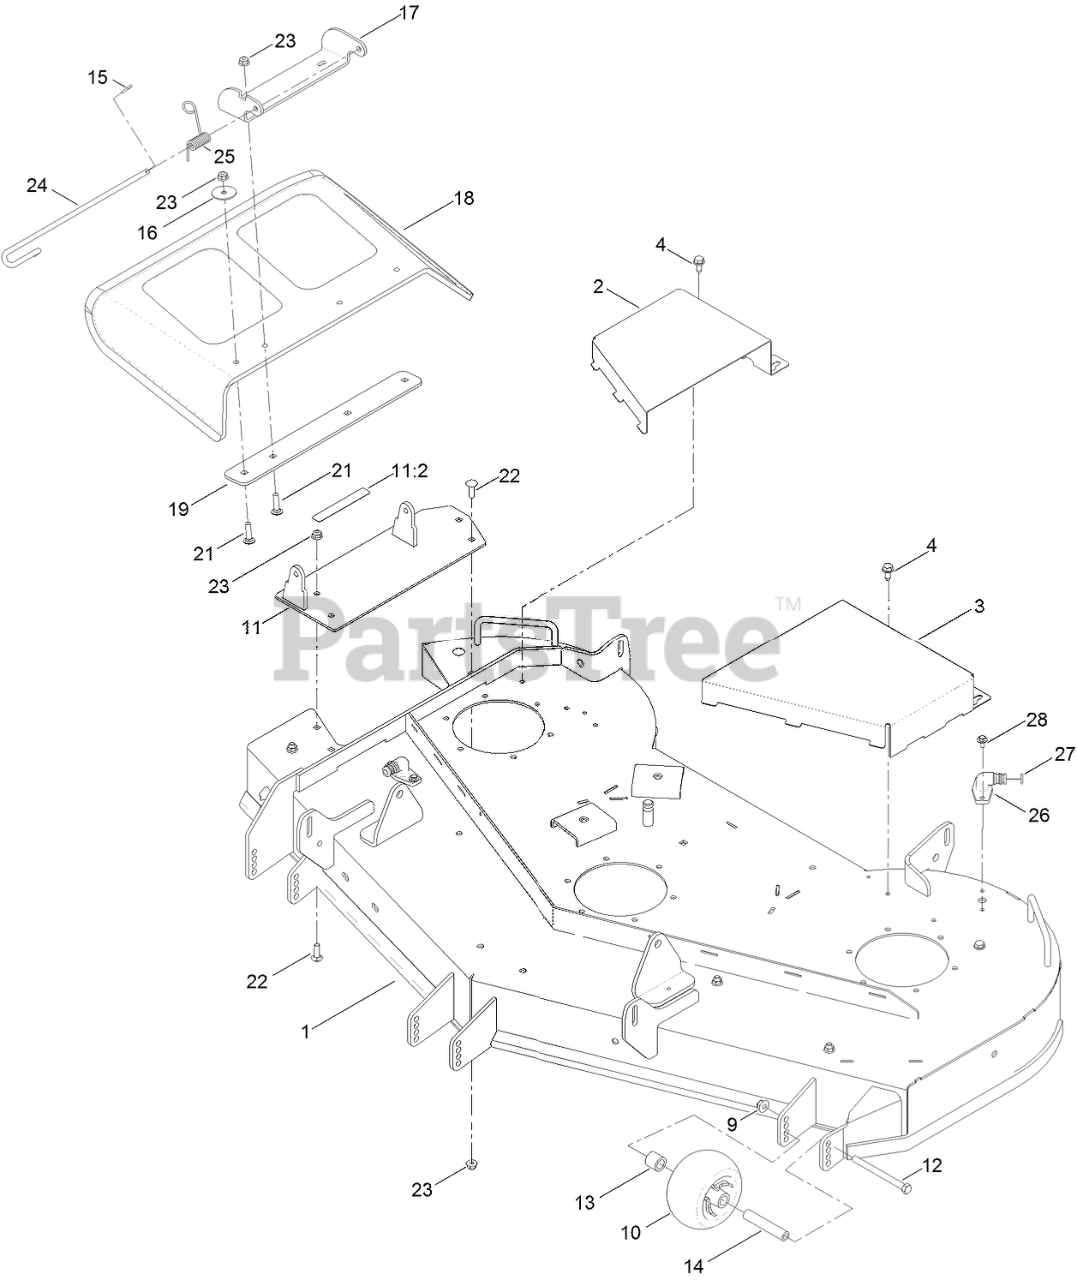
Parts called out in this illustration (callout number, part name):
1	54 INCH DECK ASM
2	COVER-BELT, RH
3	COVER-BELT, LH
4	SCREW-HWHTF
9	NUT-HF, NI
10	ROLLER-SCALP, ANTI
11	PIVOT-DEFLECTOR
11:2	DECAL-DANGER
12	SCREW-HH
13	SPACER-AXLE, REAR
14	TUBE-SPANNER
15	PIN-COTTER
16	WASHER-FLAT
17	BRACKET-DEFLECTOR, UPPER
18	DEFLECTOR
19	PLATE-DEFLECTOR
21	SCREW-CARR
22	SCREW-CARR
23	NUT-HF, NI
24	PIN-CHUTE
25	SPRING-TORSION
26	FITTING-WASHOUT
27	O-RING
28	SCREW-HHFTF
